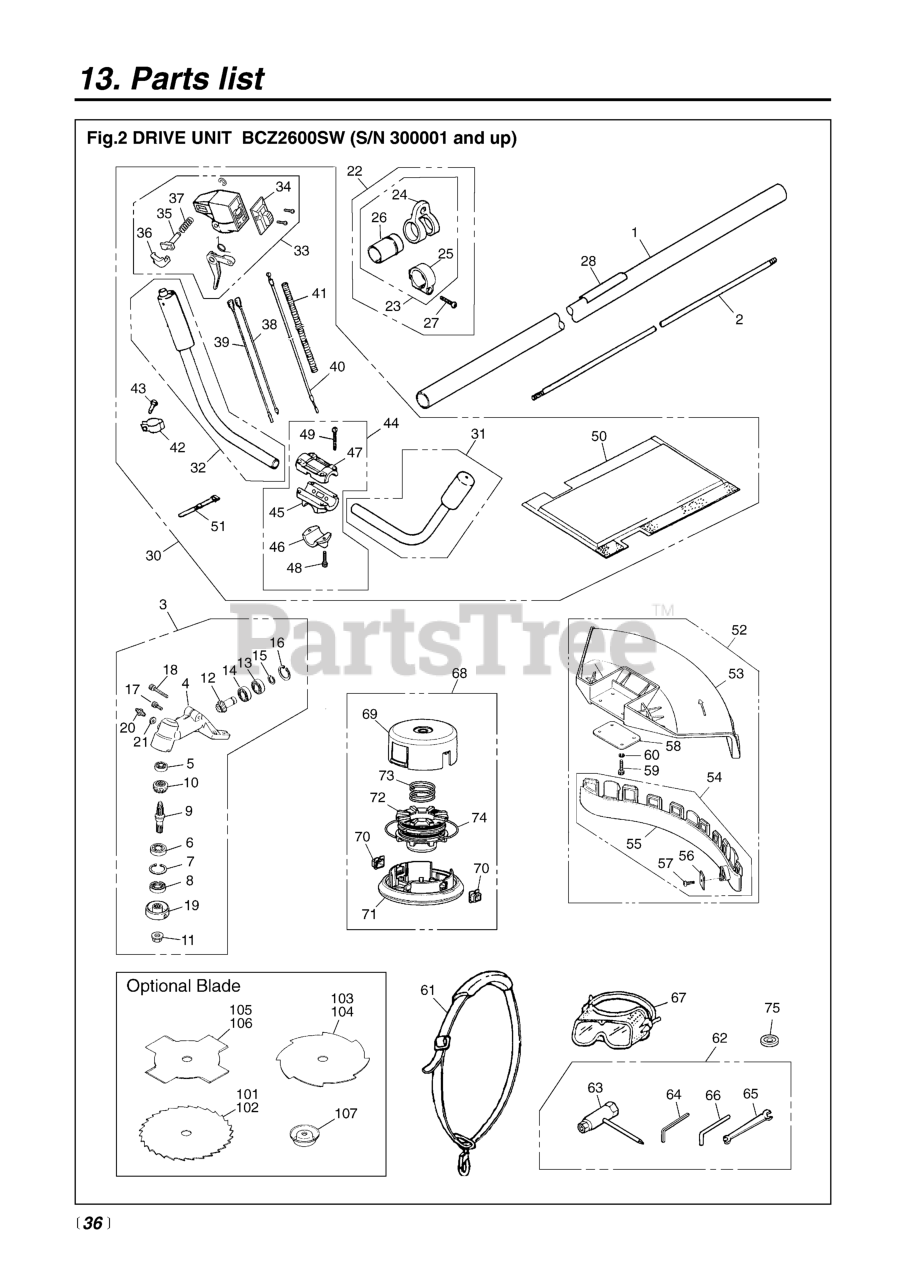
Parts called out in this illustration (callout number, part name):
1	PIPE COMP (REPLACES -12100)
2	SHAFT (RPLS -12212)
3	GEARCASE ASSY (RPLS -13000)
4	GEARCASE
7	RING, SNAP, M26 X 1.2
8	SEAL, OIL
9	SHAFT
10	GEAR
11	NUT
12	PINION
16	RING, SNAP, M24 x 1.2
17	BOLT, M5 X 10
18	BOLT
19	HOLDER (A)
20	FITTING, GREASE
21	WASHER, M6 X .8
22	HANGER ASSEMBLY
23	HANGER COMPLETE
24	HANGER
25	CLAMP
26	SLEEVE
27	SCREW, M5 x 25
28	LABEL NAME & CAUTION
30	KIT, BIKE HANDLE (BCX, BCZ)
31	HANDLE, L, COMP
32	HANDLE, R, COMP
33	LEVER ASSEMBLY
38	CORD (A), BLACK
39	CORD (B), RED
40	CABLE COMPLETE
41	TUBE
42	CLAMP
43	SCREW, M5 X 16
44	BRACKET ASSY (REPLACES -14100)
46	CAP, LOWER
47	CAP, UPPER (RPLS -14191)
48	BOLT, M5 X 22
49	BOLT, M5 X 25
50	PROTECTOR
51	BAND
52	GUARD ASSEMBLY
53	GUARD
54	PLATE COMPLETE
55	PLATE
56	BLADE
58	PLATE
59	BOLT, M5 X 16
60	WASHER, SPRING M4 x 1.3
61	STRAP ASSY. (USE 848-JC0-3610)
63	SOCKET
64	WRENCH (TOOL)
65	SPANNER, 8 X 10 (RPLS 2540- )
66	BAR
67	GOGGLE
68	TAP HEAD COMP.
69	CASE (REPLACES -15111)
70	EYELET
71	COVER (REPLACES -15131)
72	HOLDER, CORD (REPLACES-15141)
73	SPRING
74	CORD
75	HOLDER (B)
101	BLADE, 9
102	BLADE, 9
103	BLADE, 8
104	BLADE, 9
105	BLADE, 8
106	BLADE, 9
107	COVER
